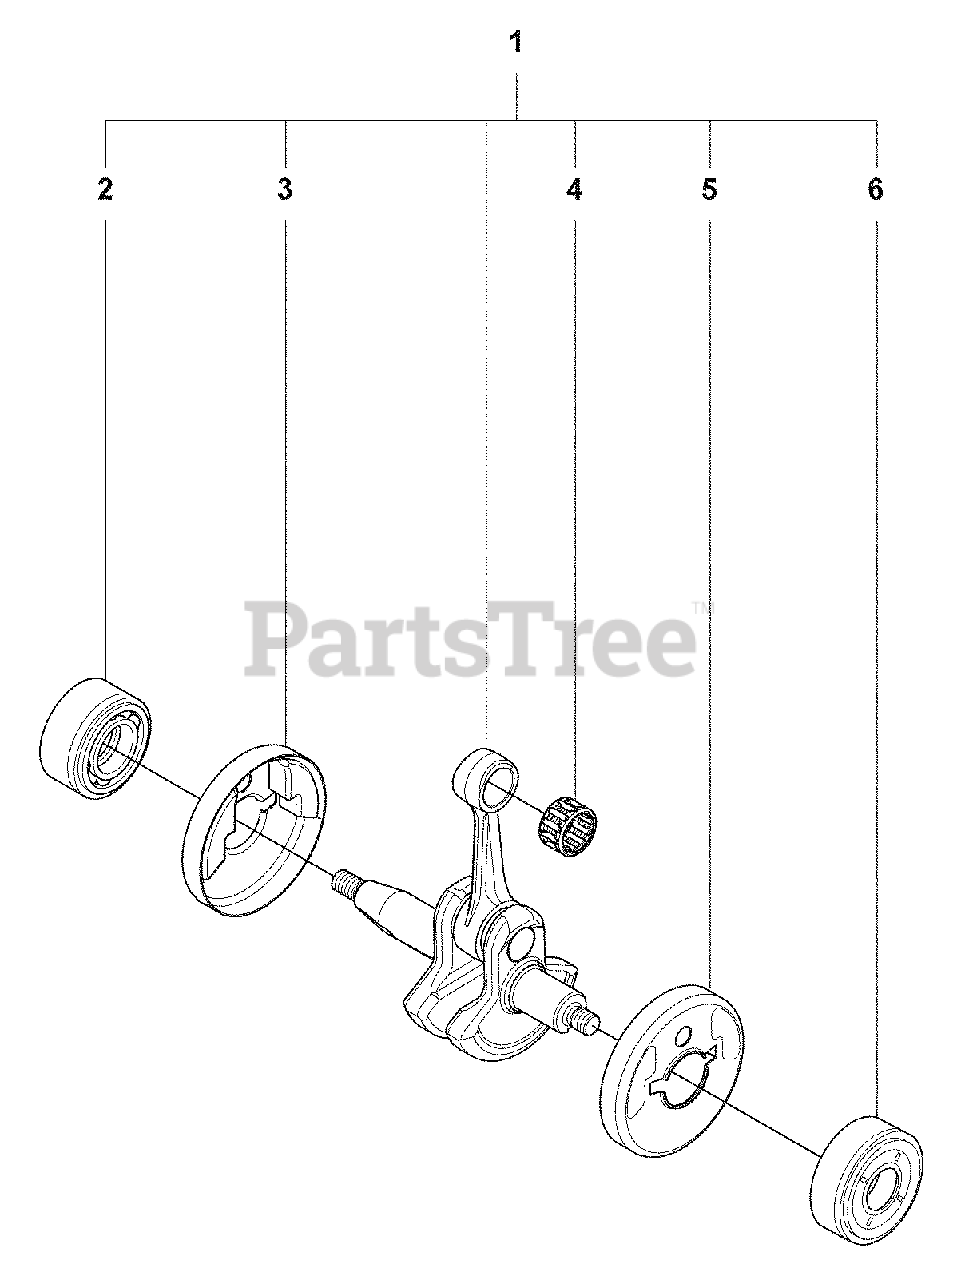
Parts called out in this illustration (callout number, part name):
1	Crankshaft
2	Bearing Cap
6	Bearing Cap
